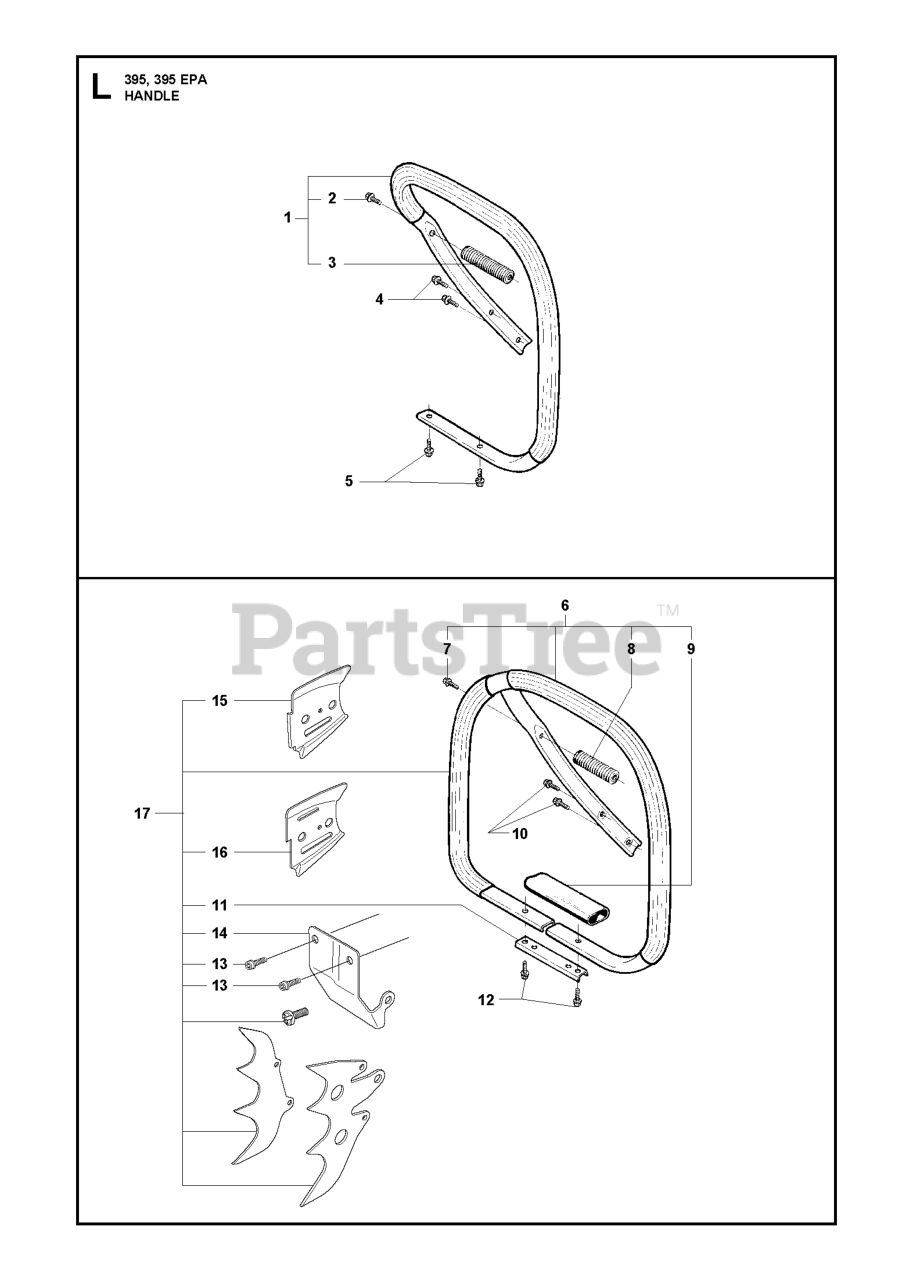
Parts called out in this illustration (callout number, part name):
1	FRONT HANDLE
6	FRONT HANDLE/WRAP
6	WRAP HANDLE, HEATED 395
13	SCREW
14	PROTECTIVE PLATE
15	GUIDE PLATE
16	GUIDE PLATE
17	395XP WRAP KIT
